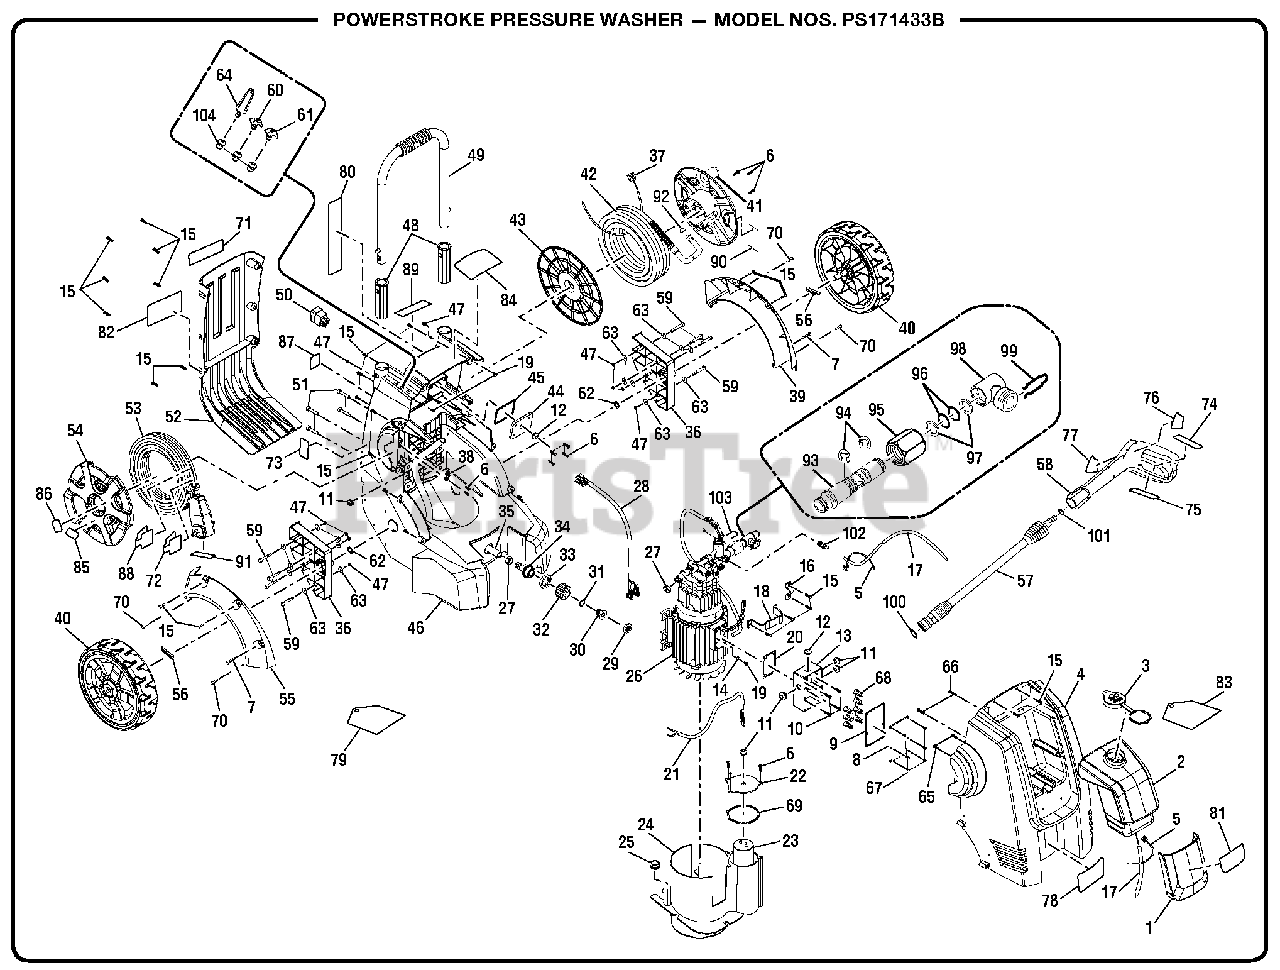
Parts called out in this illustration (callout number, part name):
1	Tank Front Panel
4	Front Housing
5	Tie Wrap (A)
6	Screw (M4.2 x 15 mm)
7	Screw (M5 x 20 mm)
8	Junction Box Cover
9	Junction Box Gasket
10	Screw (M4 x 10 mm)
11	Grommet (A)
12	Grommet (B)
13	Junction Box
14	Star Washer
15	Screw (M5 x 16 mm)
17	Detergent Hose
18	Pump Clamp
19	Screw (M4 x 6 mm)
21	Lead Wire w/Terminals
22	Capacitor Box Cover
23	Capacitor
24	Motor Cover
26	Motor Pump Assembly
28	Inner Cable
29	Water Inlet Filter
30	Water Inlet Screw
31	O-Ring (13.5 x 1.8G)
32	Water Inlet Connector
34	Hose Connector
35	Water Inlet Hose
36	Housing Insert
37	Tie Wrap (B)
38	Cord Clamp
39	Right Fender
40	Wheel Assembly
41	High Pressure Hose Reel Cover
42	High Pressure Hose
43	High Pressure Hose Reel
44	Switch Cover
46	Back Housing
47	Lock Nut (M4)
48	Handle Guide Bushing
49	Handle Assembly
50	Switch (20A)
51	Screw (M6 x 20 mm)
52	Back Shroud
53	Power Cord Assembly
54	Power Cord Reel Cover
55	Left Fender
57	Spray Wand
58	Trigger Handle Assembly
59	Screw (M4 x 40 mm)
60	Soap Nozzle
61	High Pressure Nozzle
62	Washer (17.8 mm x 12 mm x 0.5t)
63	Washer (12 mm x 4.2 mm x 0.5t)
64	Turbo Nozzle
65	Screw (M4 x 20 mm)
66	Screw (M4 x 25 mm)
67	Screw (M2.5 x 8 mm)
69	Seal (Capacitor Box Cover)
70	Screw (M2.9 x 9.5 mm)
71	Inquiries Label
72	Danger/CA Prop. 65 Label
73	Data Label
74	Trigger Handle Warning Label (French/Spanish)
75	Trigger Handle Rating Label
76	Trigger Handle Warning Label (English)
77	Trigger Handle Logo Label
78	Performance Label
79	Power Cord Reel Hang Tag
80	Starting Label
81	Front Logo Label
82	Danger Label
83	Detergent Tank Hang Tag
84	Top Logo Label
85	Power Cord Reel Unlock Label
86	Power Cord Reel Lock Label
87	On/Off Switch Label
88	Extension Cord Label
89	Carry Handle Label
90	Danger Hang Tag
91	Cord Plug Label
92	O-Ring (7.6 x 1.8G)
93	Pipe (Water Inlet)
94	Retaining Ring (E-Ring)
95	Nut (Water Inlet)
96	O-Ring (Internal)
97	Backup Ring
98	High Pressure Swivel (Water Outlet)
99	High Pressure Hose Clip
100	O-Ring (Large)
101	O-Ring (Small)
102	Detergent Injector Assembly
103	U-Pin (Switch Box)
104	Nozzle Grommet
